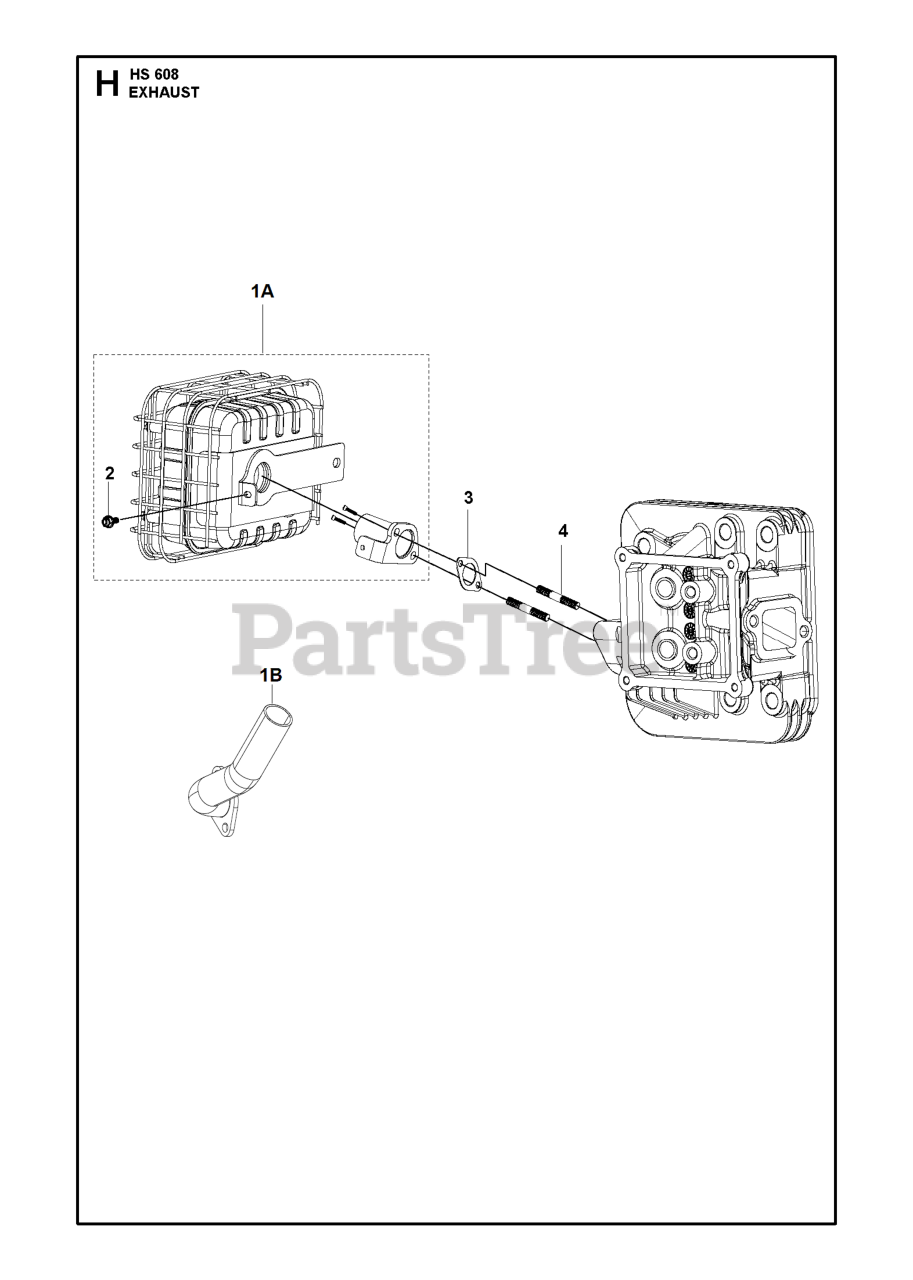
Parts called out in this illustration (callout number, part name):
1A	MUFFLER
1B	TUBE TUBE.EXHAUST.LONCIN 608.T
2	Husqvarna TBD
3	GASKET MUFFLER GASKET
4	STUD T381: 5/16-18/M8 L=34
